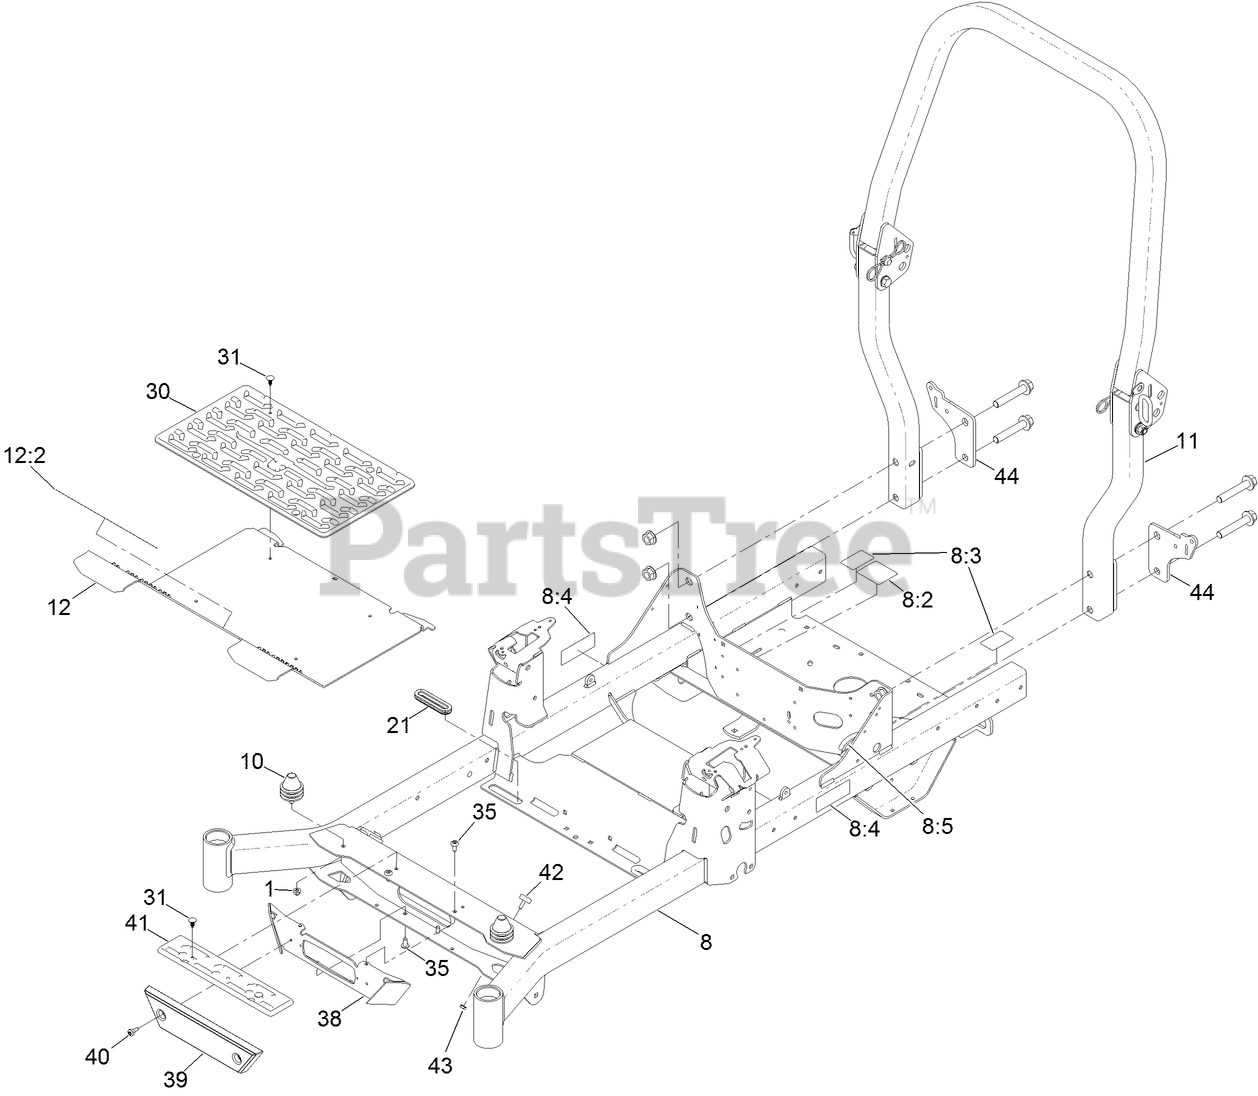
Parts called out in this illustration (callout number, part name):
1	NUT-HF, NI
8	FRAME-48/52
8:2	DECAL-ROUTING, BELT
8:3	DECAL-RELEASE, DRIVE
8:4	DECAL-WARNING
8:5	STRIP-SEAL
10	ISOLATOR
11	ASM-ROPS
12	PAN-FLOOR
12:2	DECAL-DANGER
21	GROMMET-RUBBER
30	FLOOR MAT
31	PLUG-PLASTIC
38	BRACKET-LIGHT [RED]
39	BUMPER-FRONT
40	SCREW-SHOULDER
42	BUMPER-RUBBER
43	NUT-HF
